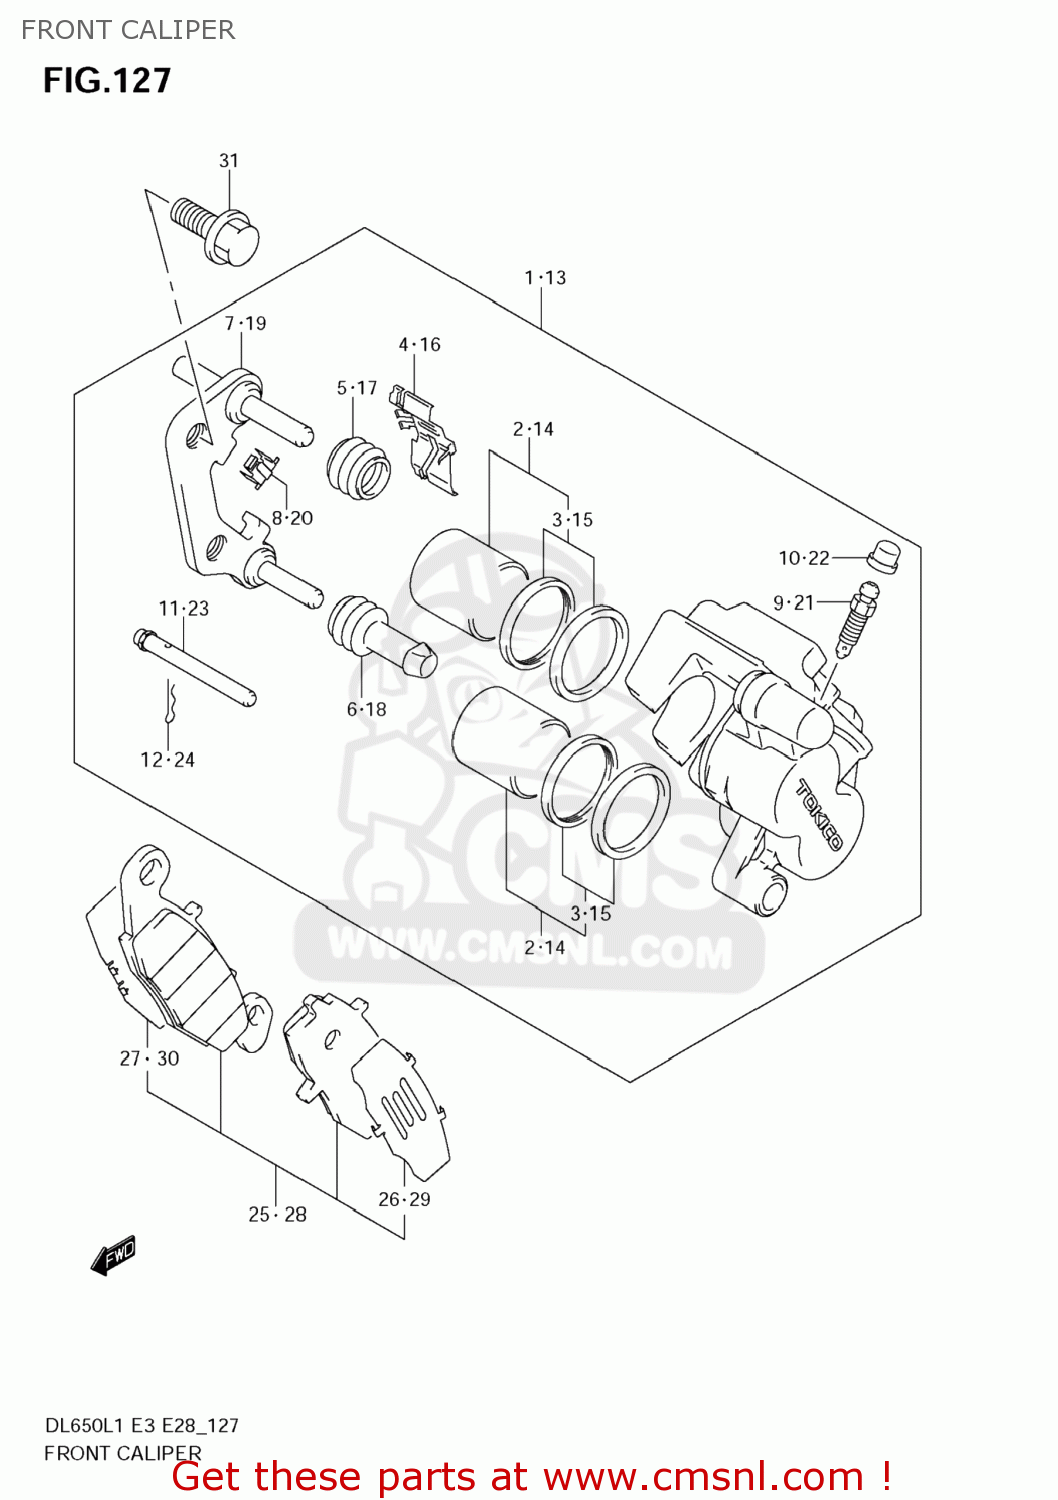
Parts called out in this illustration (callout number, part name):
1	CALIPER ASSY,FR
2	PISTON SET
3	SEAL SET,PISTON
4	SPRING,PAD,R
5	BOOT,AXLE
6	INSULATOR,AXLE
7	CARRIER,CALIPER,R
8	GUIDE,PAD
9	BLEEDER
10	CAP,BLEEDER PLUG
11	PIN,PAD
12	CLIP,PAD PIN
13	CALIPER ASSY,FR,L
14	PISTON SET
15	SEAL SET,PISTON
16	SPRING,PAD,L
17	BOOT,AXLE
18	INSULATOR,AXLE
19	CARRIER,CALIPER,L
20	GUIDE,PAD
21	BLEEDER
22	CAP,BLEEDER PLUG
23	PIN,PAD
24	CLIP,PAD PIN
25	PAD & SHIM SET,R (NAS)
26	SHIM,PAD
27	SHIM,PAD NO.2
28	PAD & SHIM SET,L (NAS)
29	SHIM,PAD
30	SHIM,PAD NO.2
31	BOLT
